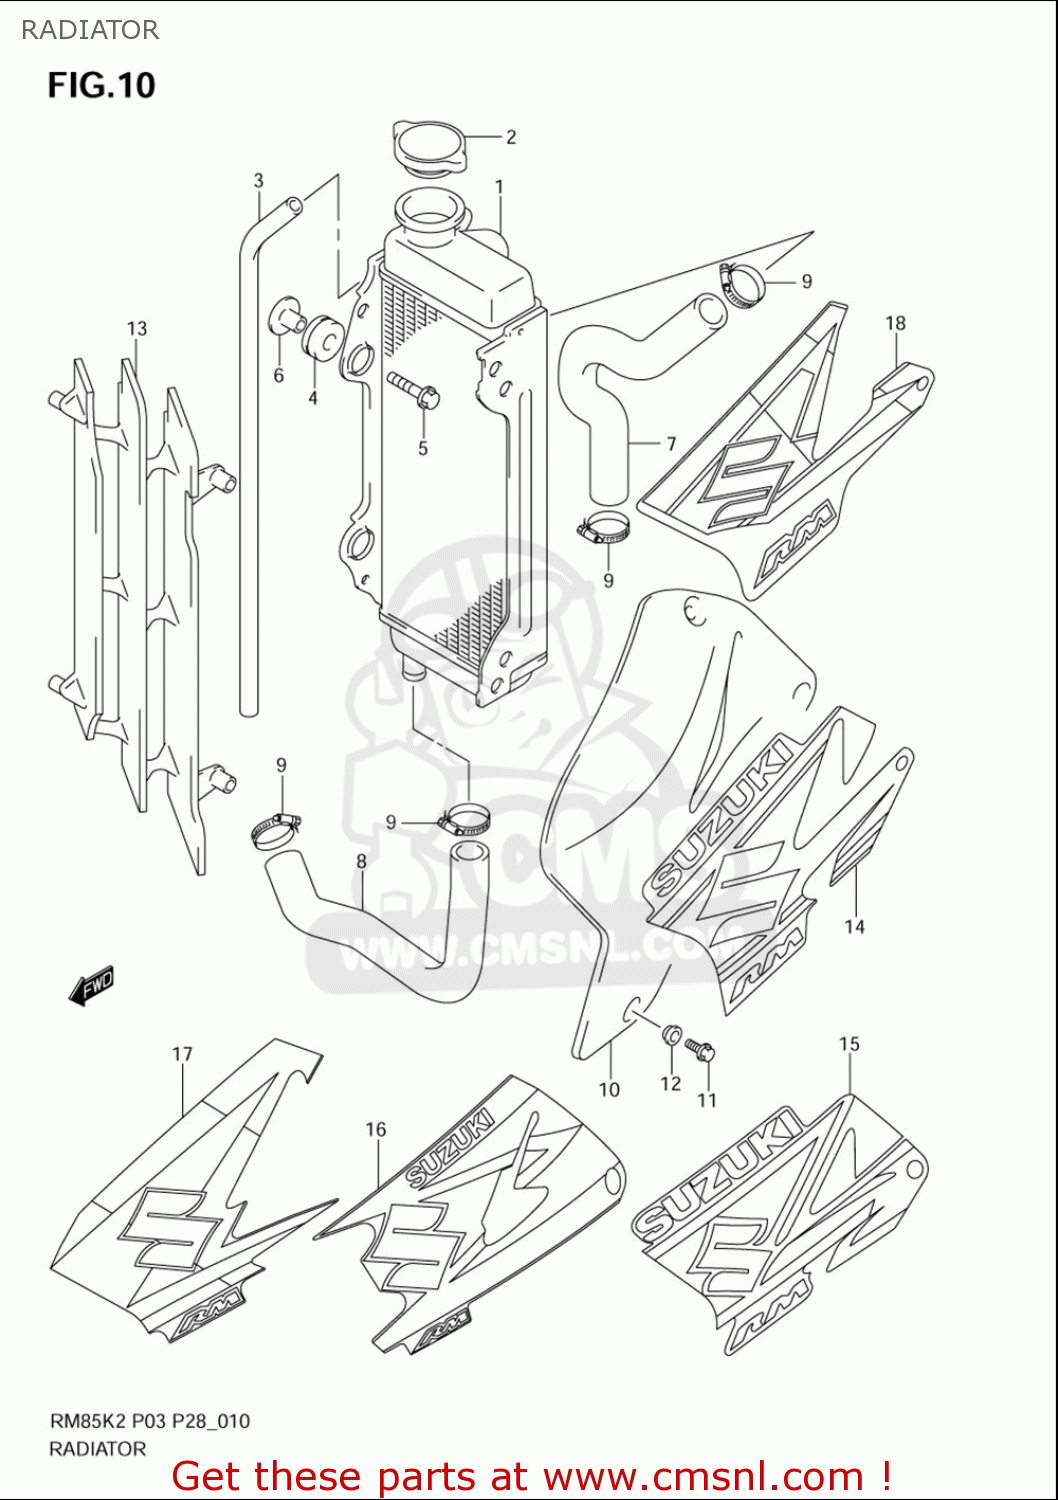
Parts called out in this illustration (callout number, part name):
1	RADIATOR,WATER
2	CAP COMP,RADIATOR
3	HOSE(5X8X1000)
4	CUSHION,RADIATOR LWR
5	BOLT(6X25)
6	SPACER(6.5X10.5X14.1)
7	HOSE,RADIATOR INLET
8	HOSE,RADIATOR OUTLET
9	CLAMP
10	COVER,RADIATOR,L(YELLOW)
11	BOLT(6X12)
12	WASHER
13	LOUVER,RADIATOR
14	TAPE,RADIATOR COVER,L
15	TAPE,RADIATOR COVER,L
16	TAPE,RADIATOR COVER,L
17	TAPE,RADIATOR COVER,L
18	TAPE,RADIATOR COVER,L
